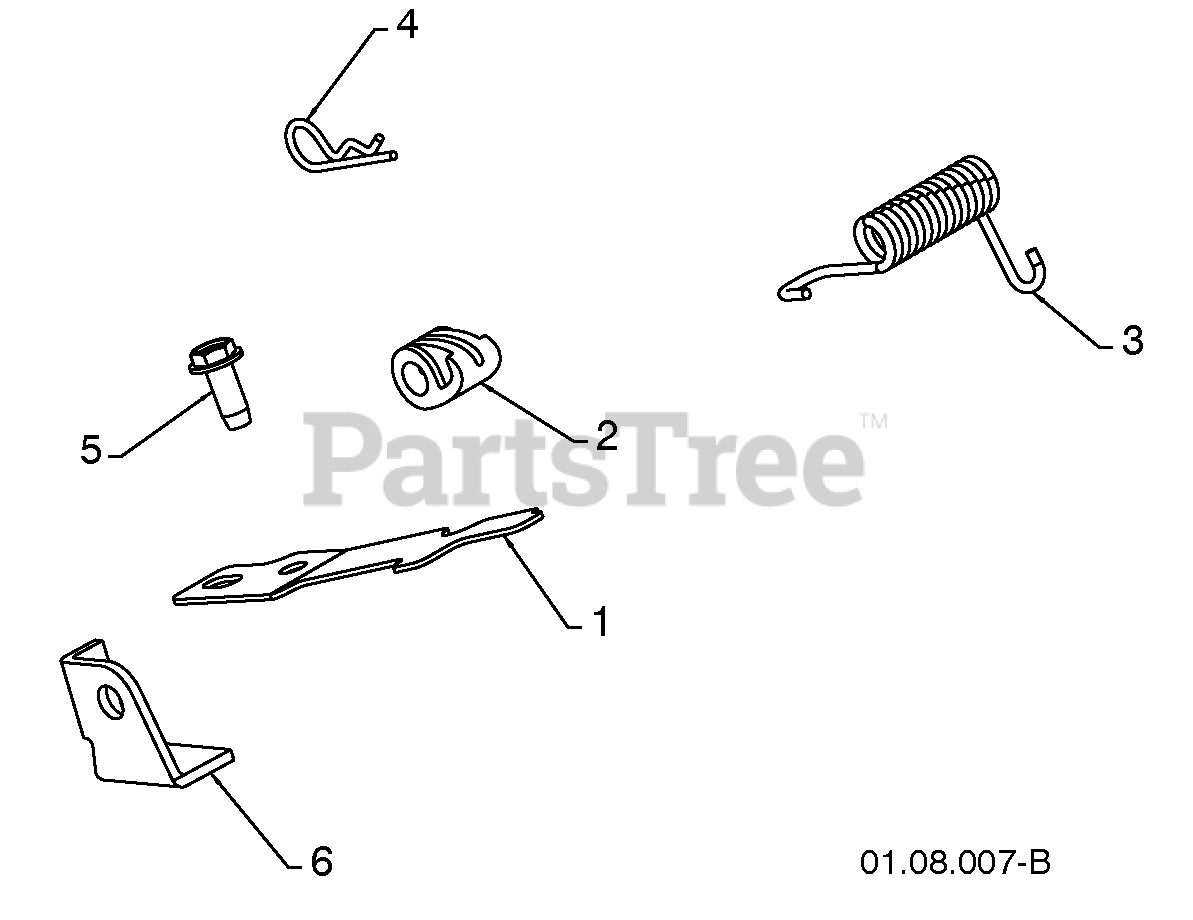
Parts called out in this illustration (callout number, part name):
1	INTERLOCK SPRING
2	INTERLOCK CAM
3	TORSION SPRING
4	RETAINER
5	SCREW 1/4-20 X .625
6	INTERLOCK STOP
